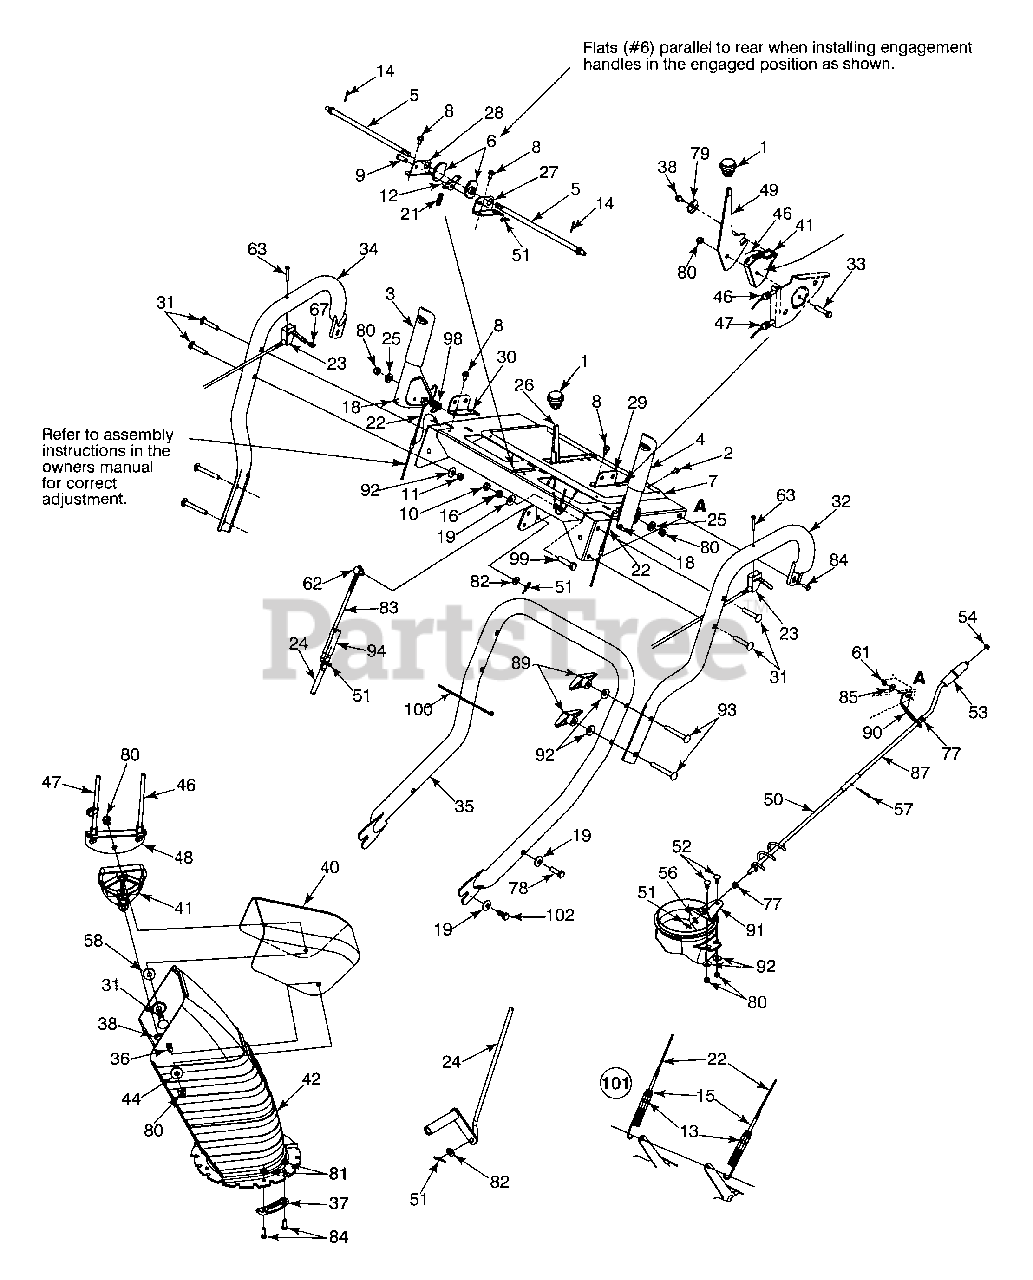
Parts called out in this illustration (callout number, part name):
1	Shift Knob
2	Truss Mach B-Tapp Scr #10-16 x .50 Gr. 5
3	Engagement Handle RH Black
4	Engagement Handle LH Black
5	Cam Rod
6	Cam Handle Lock
9	Clevis Pin.31 Dia. x 1.0" Lg.
10	Hex Nut 3/8-24 Gr. 5
11	Hex Nut 5/16-18 hd. Gr. 5
12	Cam Lock Pawl
13	Hex Ins. Locknut 1/4-20
14	Cotter Pin 3/32 x .75
15	Extension Spring
16	Compression Spring .39 ID x .88 Lg
18	Rubber Bumper
19	Cupped Washer.401 ID x .870 OD x .063
21	Compression Spring .36 DIA x 1.0" LG.
22	Clutch Cable
23	Trigger Assembly
24	Lower Shift Rod
25	Washer (special)
31	Carriage Bolt 5/16-18 x 1.75" Lg.
33	Hex Cap Scr. 5/16 - 18 x 1.50" Lg. Gr. 5
36	Carriage Bolt 5/16-18 x 1.00" Lg
37	Chute Flange Keeper
38	Hex HL Index Washer Screw 1/4-15 X .75
40	Upper Chute Remote Tilt
41	Cable Guide
42	Lower Chute Remote Tilt
44	Flat Washer.349 ID x .879 OD x .063
46	Chute Control Cable 66"
47	Chute Control Cable w/clip
52	Carriage Bolt 5/16-18 x .75 Gr. 2
53	Knob 1.0 x 3.2
54	Push Nut 3/8" Rod
56	Flat Washer.375 ID x .738 OD X.063
57	Internal Cotter Pin
58	Flat Washer.344 ID x 1.125 OD x .125
61	Hex Flg. L-Nut 1/4-20 Gr. F Nylon
62	Adjustment Ferrule
63	Oval C-Sunk Screw #10-24 x 1.75
77	Plastic Bushing .380 ID
78	Hex Screw 3/8-16 x 1.75 Gr.5 w/patch
79	Contour Washer
80	Hex Ins. L-Nut 5/16-18 Gr. 5
81	Hex L-Flanged Nut 1/4-20 Gr. "F"
82	Flat Washer .344 1 D x .688 OD x .065
83	Upper Shift Rod
84	Hex Screw 1/4-20 x .75" Lg. Gr. 5
89	Wingnut Knob, 5/16-18
92	Cupped Washer.340 ID x .872 OD x .06
93	Carriage Bolt 5/16-18 x 2.50
94	Connector - Shift Rod
98	Torsion Spring .44 ID
99	Hex Scr 3/8-24 x 1.50 Gr. 5
100	Cable Tie
101	Auger/Drive Cable Assembly
102	Hex Screw 3/8-16 x .880 Gr. 5
103	Hex Screw 1/4-20 x 1.00 Gr. 5
